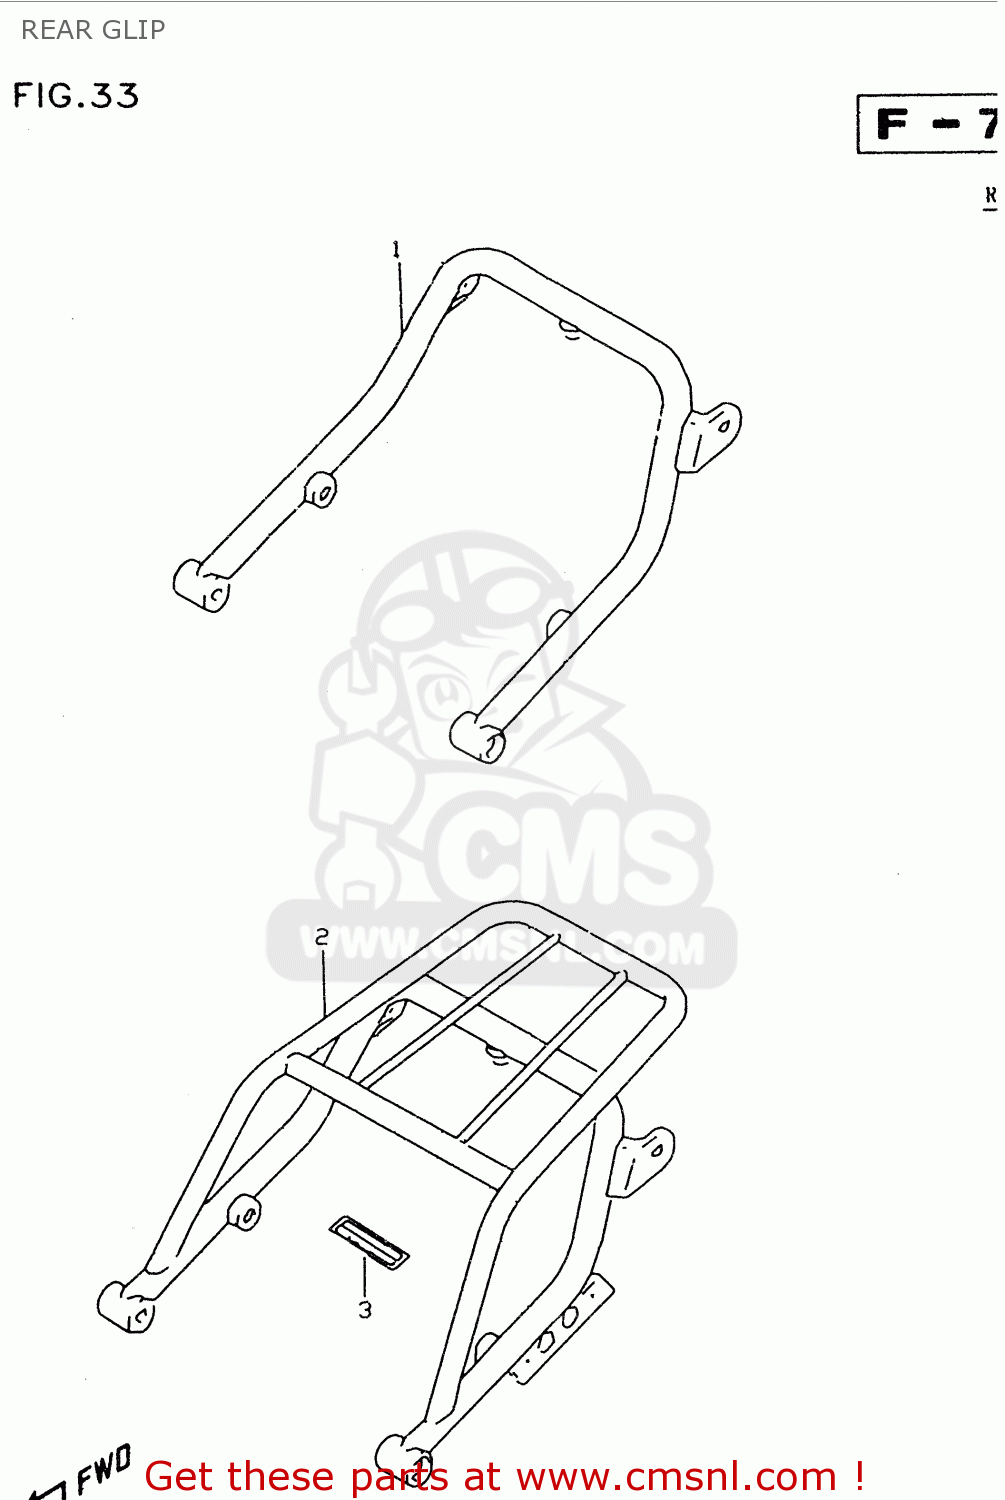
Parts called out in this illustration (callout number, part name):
1	GRIP,RR
2	CARRIER,SPORT
3	LABEL,WARNING
